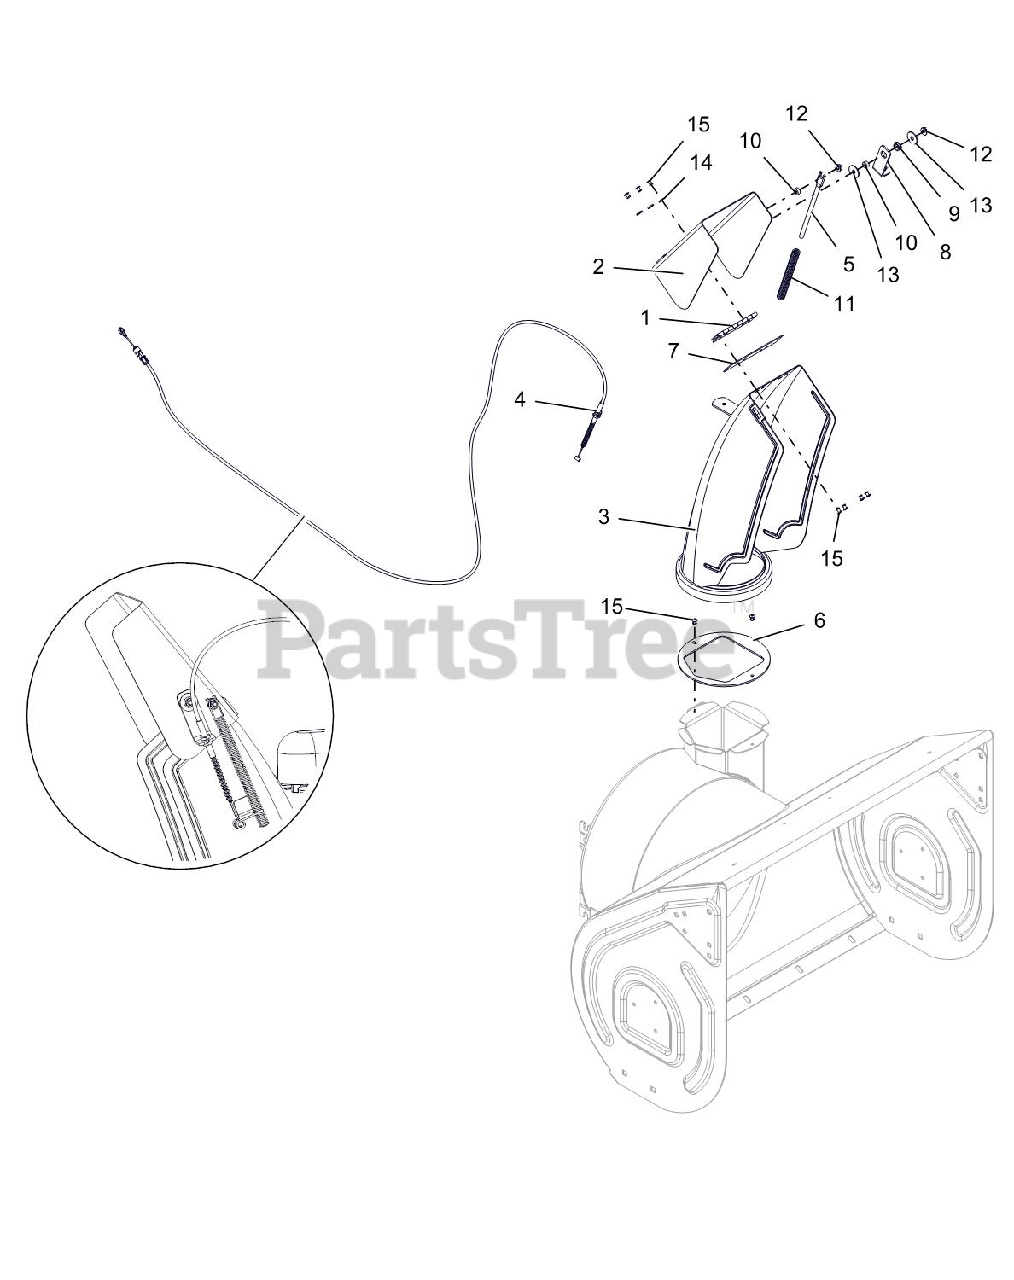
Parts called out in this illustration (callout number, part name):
2	CAP, LARGE REMOTE (W/DECAL)
3	CHUTE,DISCHARGE,NOTCHED,QT
4	CABLE, DEFLECTOR - DELUXE
5	ROD, DEFLECTOR CAP
6	BAFFLE, DISCHARGE NECK
7	CAP SEAL 5.50
8	BRACKET, CABLE ANCHOR
9	BUSHING, POLYLINER-.50 SNAPIN
10	BSHG-SLV .265X.500X.219
11	SG-COMP .08X.40X6.50 14#/IN
12	@NUT-LK-CTR-FLG .25-20 YWZC
13	WSHR-FL-STL .281X1.000X.063
14	WSHR-FL-STL .196X.500X.06 YZ
15	RVT-POP .187 YZ
